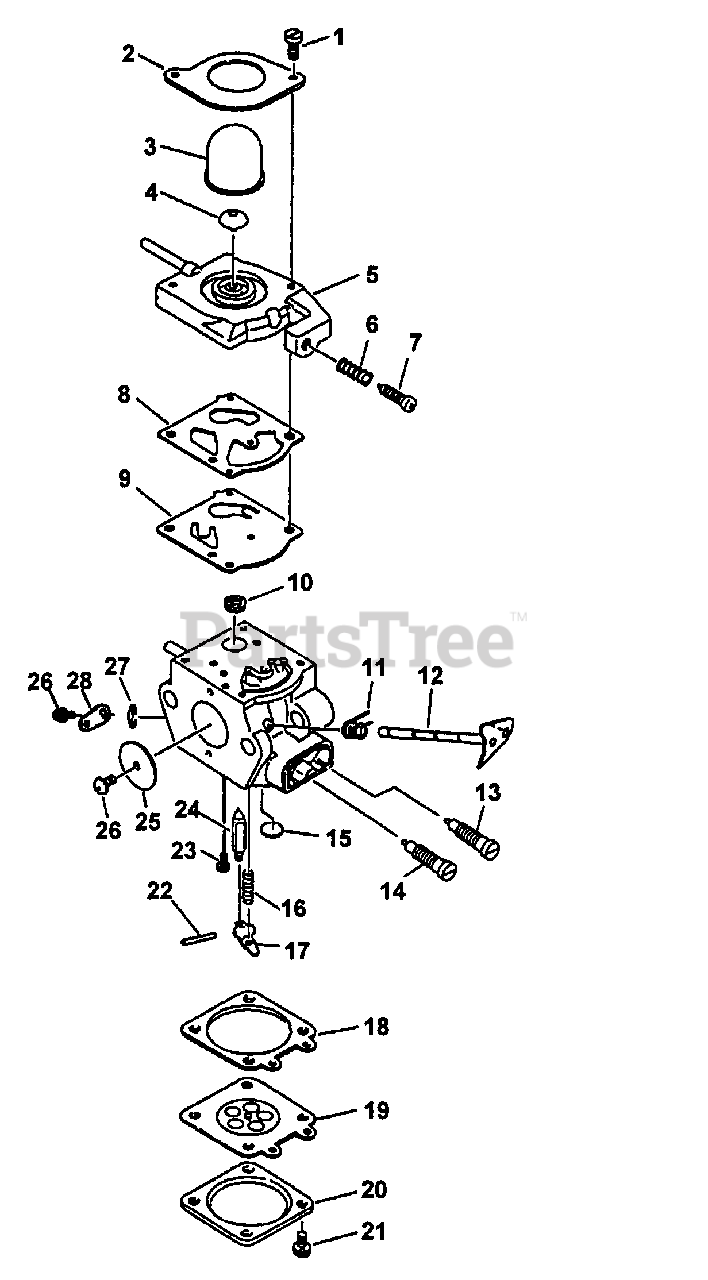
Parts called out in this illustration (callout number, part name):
1	SCREW, PUMP COVER
2	RETAINER, PURGE BULB
3	BULB, PURGE
4	VALVE, CHECK
5	COVER, PUMP
6	SPRING, IDLE ADJUST
7	SCREW, IDLE ADJUST
8	GASKET, PURGE
9	DIAPHRAGM, PURGE
10	STRAINER
11	SPRING, THROTTLE RETURN
12	SHAFT, THROTTLE
13	NEEDLE - HIGH SPEED
14	NEEDLE - LOW SPEED
15	PLUG, WELCH
16	SPRING, METERING LEVER
17	LEVER, METERING
18	GASKET, METERING
19	DIAPHRAGM, METERING
20	COVER, METERING
21	SCREW, METERING COVER
22	PIN, METERING LEVER
23	SCREW, METERING LEVER PIN
24	VALVE, INLET NEEDLE
25	VALVE, THROTTLE
27	RING, RETAINING
28	LEVER, THROTTLE
